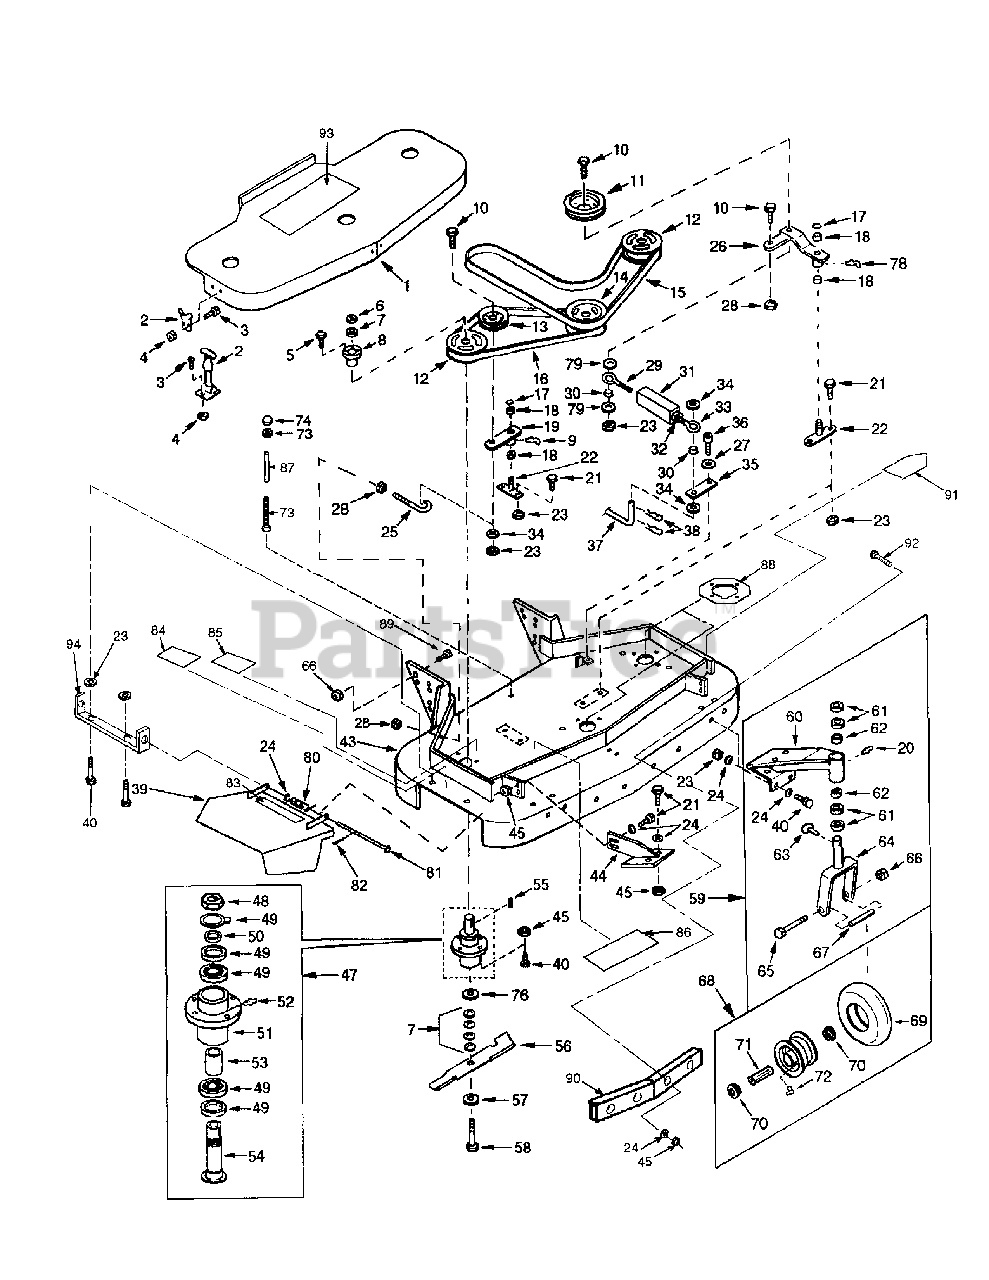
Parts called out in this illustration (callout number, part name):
1	Deck Cover
2	Rubber Latch
3	Machine Screw, 10-24 x 1/2 Round Hd.
4	Hex Nut, 10-24 Nylock
5	Cap Screw, 1/4-20 x 3/4 Hex Hd.
6	Hex Nut, 5/8-11
7	Blade Spacer
8	Pulley Bushing
9	Grease Fitting, 1/4-28, 90 degree
10	Cap Screw, 3/8-16 x 2-1/2 Hex Hd.
11	Idler, Deck Take-up
12	Deck Pulley
13	Deck Idler
14	Double Pulley
15	Drive Belt
16	Drive Belt
17	E-Ring, External
18	Sintered Bushing
19	Pivot Arm, Deck Idler Pulley
20	Grease Fitting, 1/4-28, Taper, Str.
21	Cap Screw, 3/8-16 x 1 Hex Hd.
22	Idler Pivot
23	Hex Nut, 3/8-16 Nylock
24	Flat Washer, 3/8, Small O.D.
25	Rod, Belt Tensioner
26	Pivot Arm, Deck Take-up Idler Pulley
27	Shim Washer, 3/4 x 1/2 x 1/16
28	Hex Nut, 3/8-16
29	Eyebolt, L.H.
30	Sleeve
31	Turnbuckle
32	Hex Nut, 5/16-18
33	Eyebolt, R.H.
34	Flat Washer, 3/8, Large O.D.
35	Clutch Link
36	Shoulder Bolt, 1/2 X 3/8
37	Rod, Blade Clutch
38	Hairpin, 3/8-7/16
39	Discharge Chute
40	Cap Screw, 3/8-16 x 1-1/4 Hex Hd.
41	Cap Screw, 1/2-13 x 1-1/4 Hex Hd.
42	Lock Washer, 1/2 Heavy
43	Cutter Deck
44	Caster Support
45	Hex Nut, 3/8-16 Stover
46	Belt Guide
47	Spindle Assembly
48	Hex Nut, 1-1/8-12 UNF, Jam
49	Kit, Spindle Repair
50	Seal Spacer
51	Spindle Housing
52	Grease Fitting
53	Internal Spacer
54	Spindle
55	Key, 1/4 x 1/4 x 2
56	Rotary Blade, 16-1/2
57	Flat Washer, 5/8
58	Cap Screw, 5/8-11 x 9-1/2 Hex Hd.
59	Caster Assembly
60	Caster Bracket
61	Caster Spacer
62	Bushing, Caster Bracket
63	Lynch Pin, 7/16 x 1-7/8
64	Caster Yoke
65	Cap Screw, 1/2-13 x 5-1/2 Hex Hd.
66	Hex Nut, 1/2-13 Nylock
67	Sleeve, Caster Wheel Bearing
68	Caster Wheel Assembly
69	Tire, Caster Wheel
70	Bearing Retainer, Caster Wheel
71	Roller Bearing, Caster Wheel
72	Grease Fitting, 1/4-28, 45°.
74	Protective Cap
76	Flat Washer, 1-1/2 x 5/8 x .055
77	Flat Washer, 3/8, Thick
78	Grease Fitting
79	Flat Washer, 5/16 USS
80	Torsion Spring
81	Deflector Pivot Pin Ass'y
82	Cotter Pin, 1/8 x 1
83	Decal, "Width Cut"
84	Decal, Rotating Blade
85	Decal, Warning Safety
86	Decal, Warning Shield
87	Spacer, Belt Guard
88	Plate, Spindle Backing
89	Bolt, Carriage
90	Bumper, 48"
91	Decal, Danger
92	Bolt, Carriage
93	Label, Command Deck
94	Bracket, Deflector
95	Bolt, Carriage
